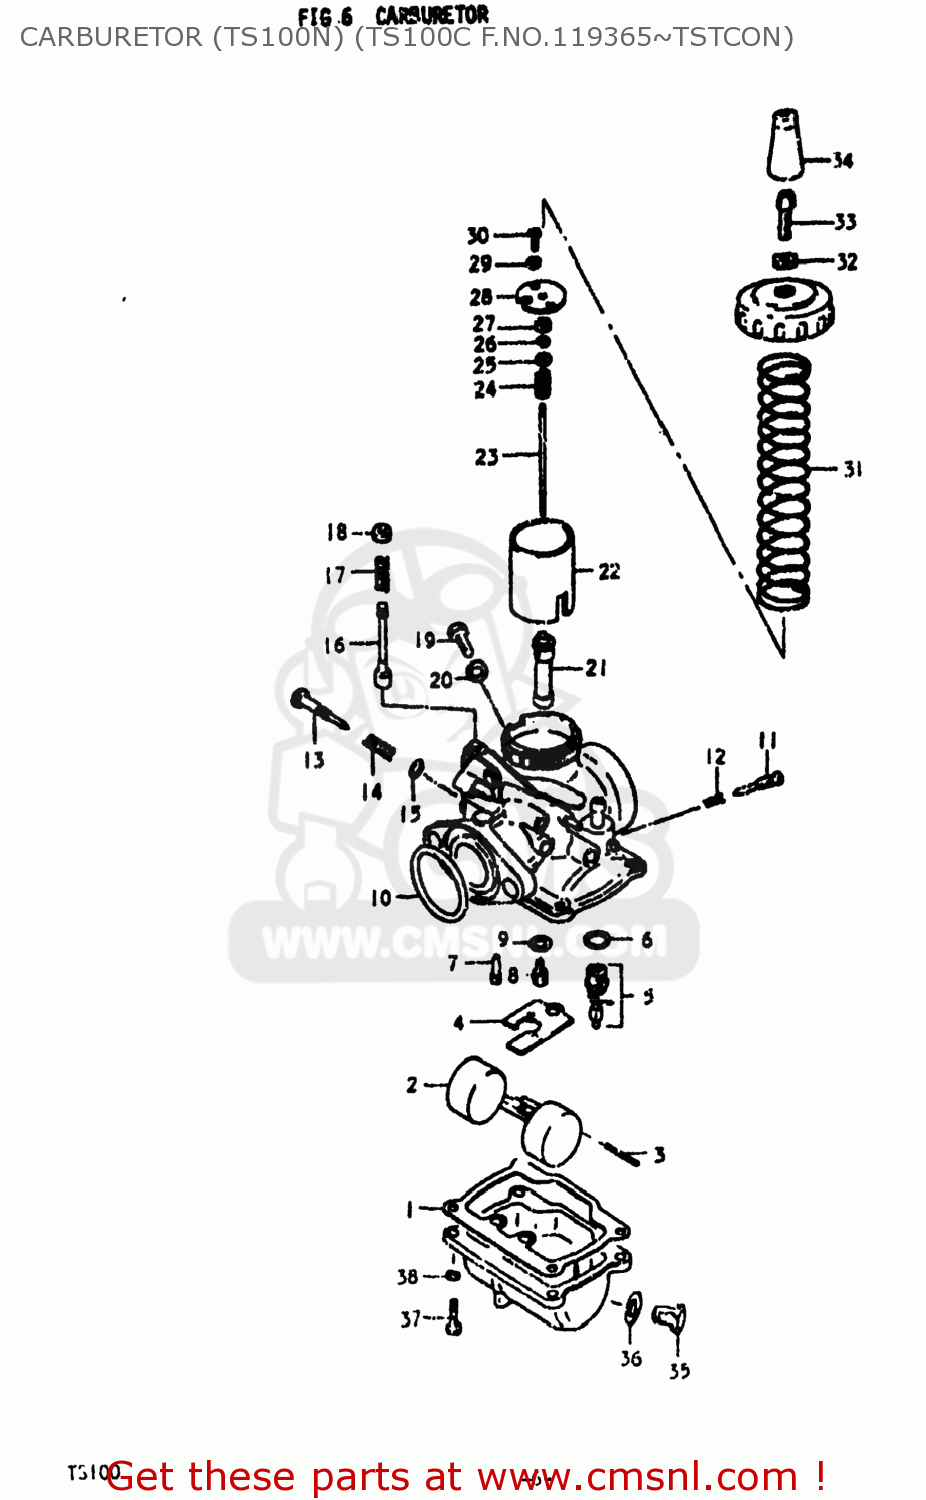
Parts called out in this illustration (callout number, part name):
1	GASKET,FLOAT CHAMBER (NAS)
2	FLOAT
3	PIN,FLOAT
4	PLATE
5	VALVE ASSY,NEEDLE
6	GASKET,VALVE SEAT (NAS)
7	JET,PILOT(17.5)
8	JET,MAIN(115)
9	WASHER
10	O RING
11	SCREW,PILOT AIR
12	SPRING
13	SCREW,THROTTLE STOP
14	SPRING,PILOT
15	O-RING
16	VALVE,STARTER
17	SPRING
18	RUBBER,THROTTLE VALVE CAP
19	BOLT
20	GASKET,THRO VALVE INSPECTION (NAS)
21	JET,NEEDLE
22	VALVE,THROTTLE
23	NEEDLE JET
24	SPRING
25	WASHER,JET NEEDLE
26	CLIP
27	RING
28	PLATE,THROTTLE VALVE
29	LOCK WASHER
30	SCREW
31	SPRING,THROTTLE VALVE
32	NUT
33	ADJUSTER,CABLE
34	CAP
35	PLUG
36	GASKET,DRAIN,PLUG (NAS)
37	SCREW
